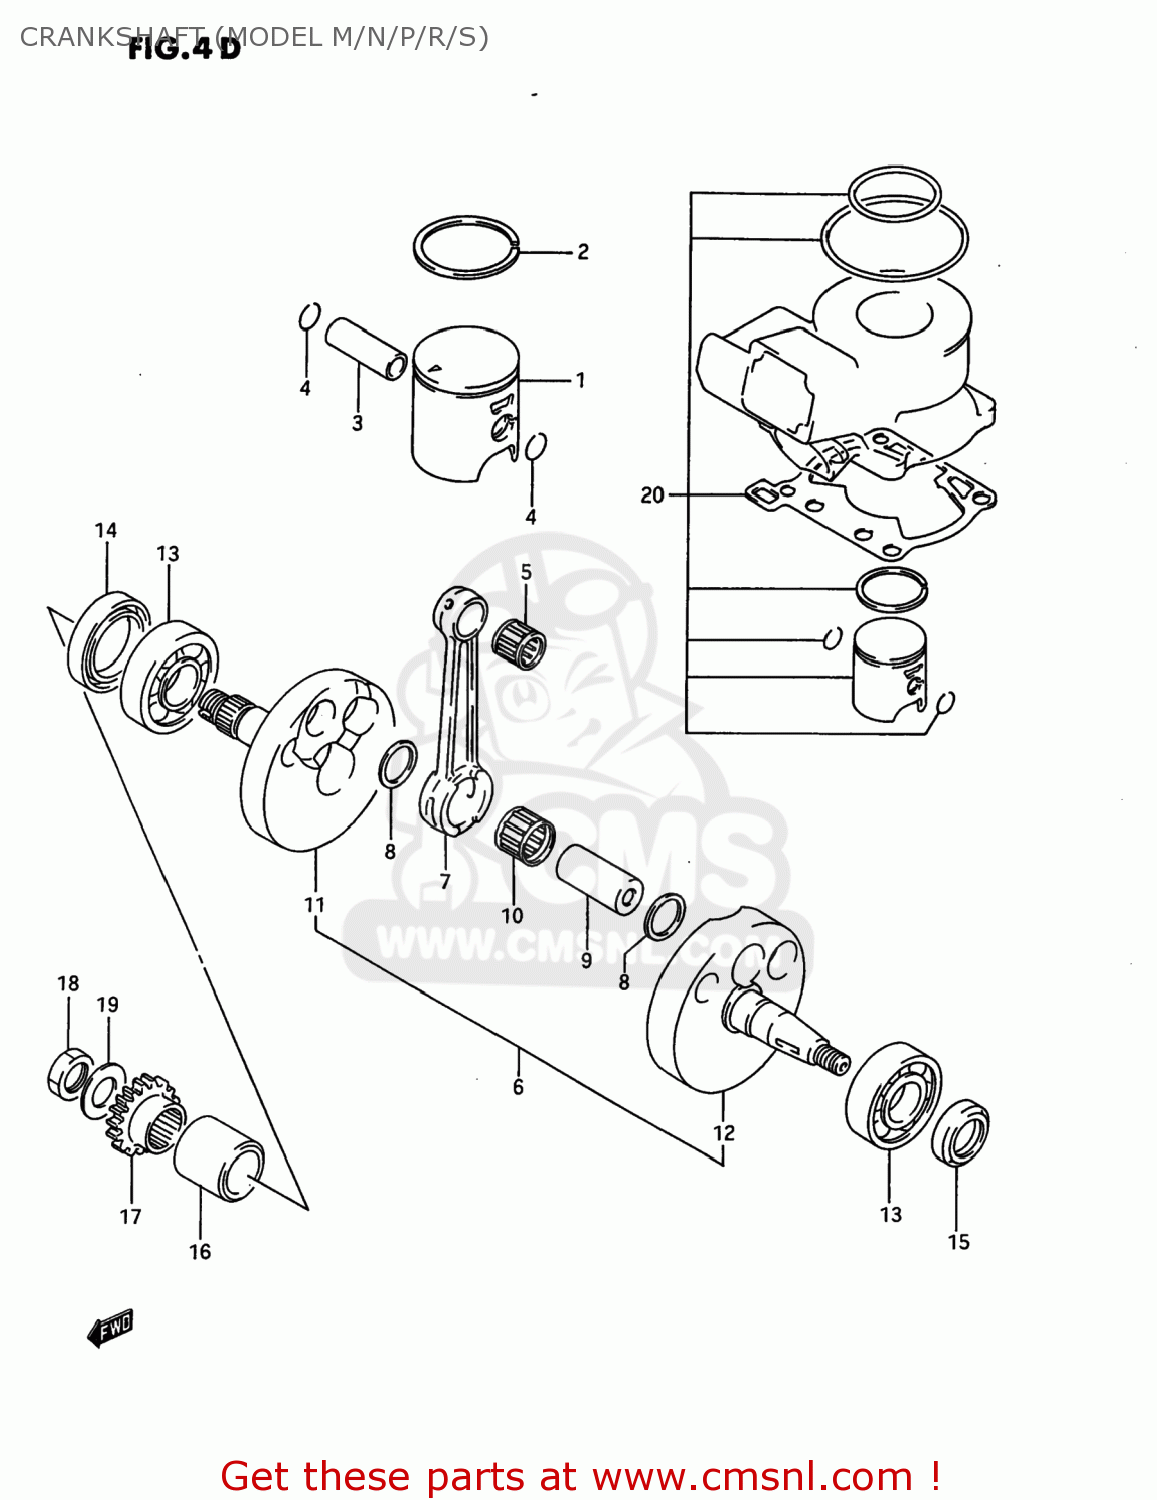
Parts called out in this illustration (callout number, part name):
1	PISTON
2	RING,PISTON
3	PIN,PISTON
4	RING,SNAP 14MM
5	BEARING(14X18X16)
6	CRANKSHAFT ASSY
7	ROD,CONNECTING
8	WASHER
9	PIN,CRANK
10	BEARING(20X26X13.7)
11	CRANKSHAFT,RIGHT
12	CRANKSHAFT,LEFT
13	BEARING(20X52X15)
14	SEAL,OIL(30X40X7)
15	SEAL,OIL(18X30X6)
16	SPACER,PRIMARY DRIVE GEAR
17	GEAR,PRIMARY DRIVE (NT:
18	NUT
19	WASHER
20	TOP END KIT,ENGINE
